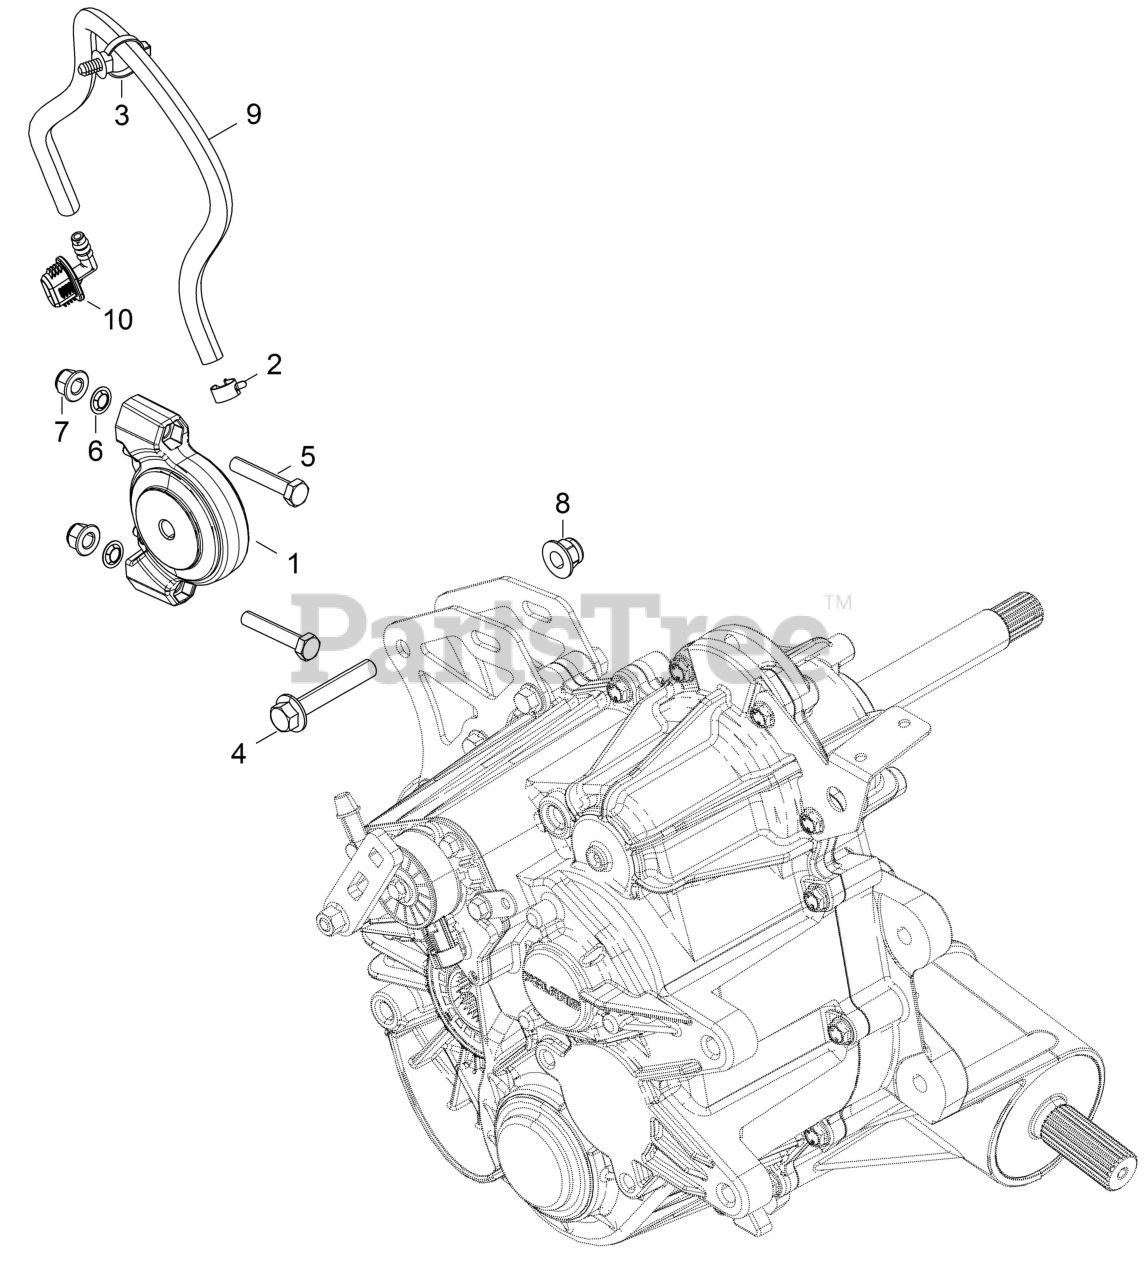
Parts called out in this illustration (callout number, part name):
1	MOUNT-ISOLATOR,DRIVELINE
2	CLAMP-HOSE, 17/32, GREEN
3	CLIP-ROUTING
4	BOLT-M10X1.25X60,HXFLG-OLIVE D
5	SCR-HH M8X1.25X45 8.8 ZOD
7	NUT-M8X1.25,FLG,NYLOC-OLIVE D
8	NUT-M10X1.25,FLG,NYLOC-OLIVE D
9	LINE, FUEL 54 CM
10	FITTING, VENT LINE, 90
